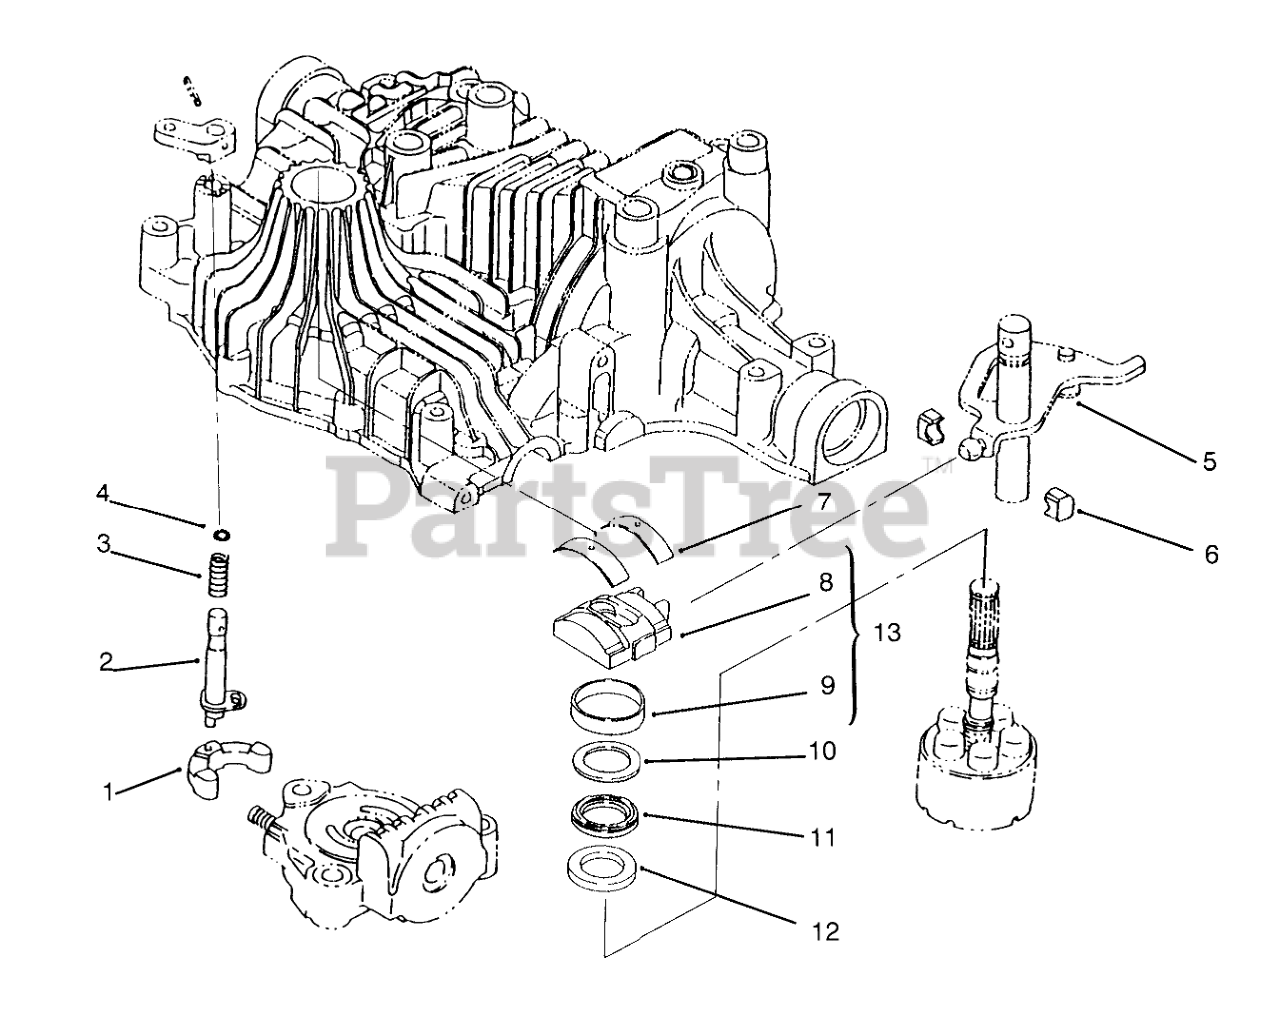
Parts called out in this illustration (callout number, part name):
1	Arm (Only On: 72043,72063,72103)
2	Shaft-Bypass (Only On: 72043,72063,72103)
3	Spring (Only On: 72043,72063,72103)
4	Packing (Only On: 72043,72063,72103)
5	Block Set INCL 6 (Only On: 72043,72063,72103)
7	Thrust Metal (Only On: 72043,72063,72103)
10	Plate-Thrust (Only On: 72043,72063,72103)
11	Bearing (Only On: 72043,72063,72103)
12	Plate-Thrust (Only On: 72043,72063,72103)
13	Swash Plate INCL 8-9 (Only On: 72043,72063,72103)
